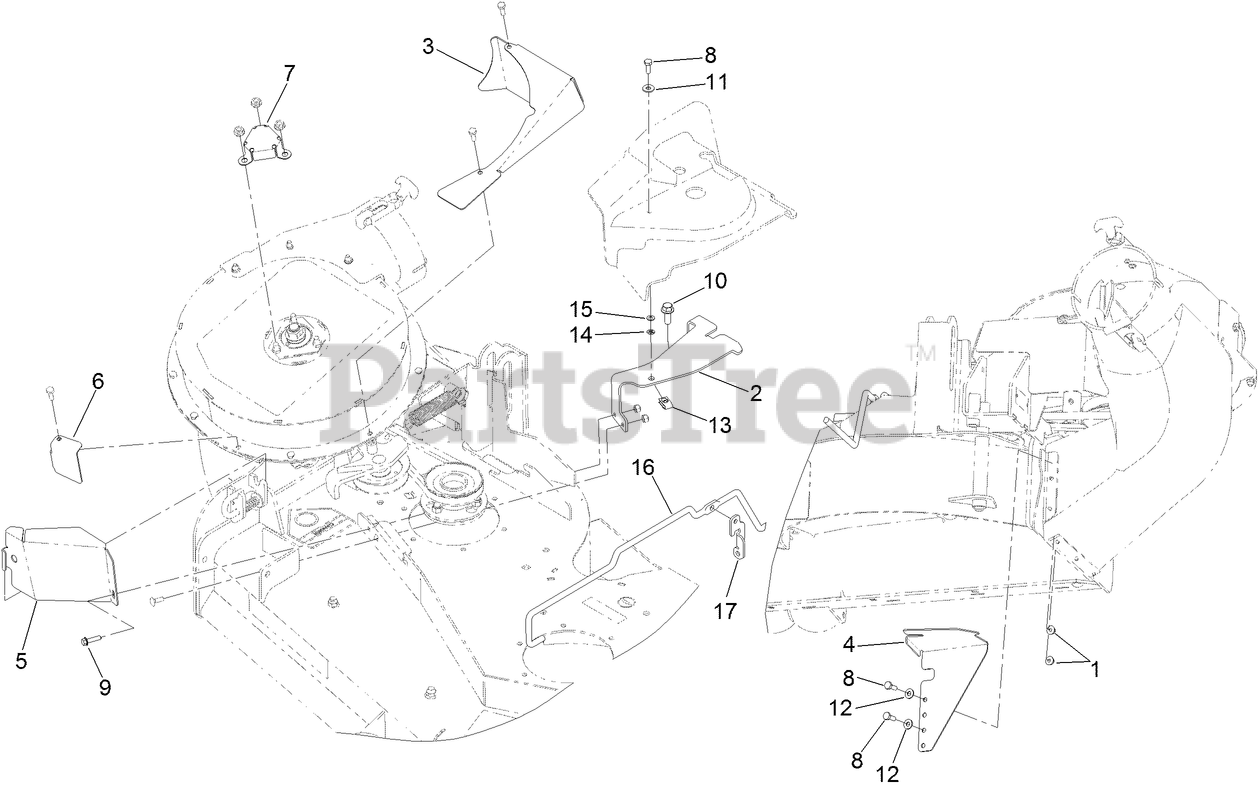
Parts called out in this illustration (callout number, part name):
1	NUT-HF
2	BRACKET-COVER
3	GUARD-TOP
4	GUARD-BAGGER
5	GUARD-BAGGER
6	GUARD-LEFT
7	COVER-NUT
8	SCREW-HH
9	SCREW-HHF
10	SCREW-HHF
11	WASHER-FLAT
12	WASHER-FLAT
14	NUT-RETAINER
15	WASHER-FLAT
16	ROD-SUPPORT, LOWER
17	BRACKET-LOWER
